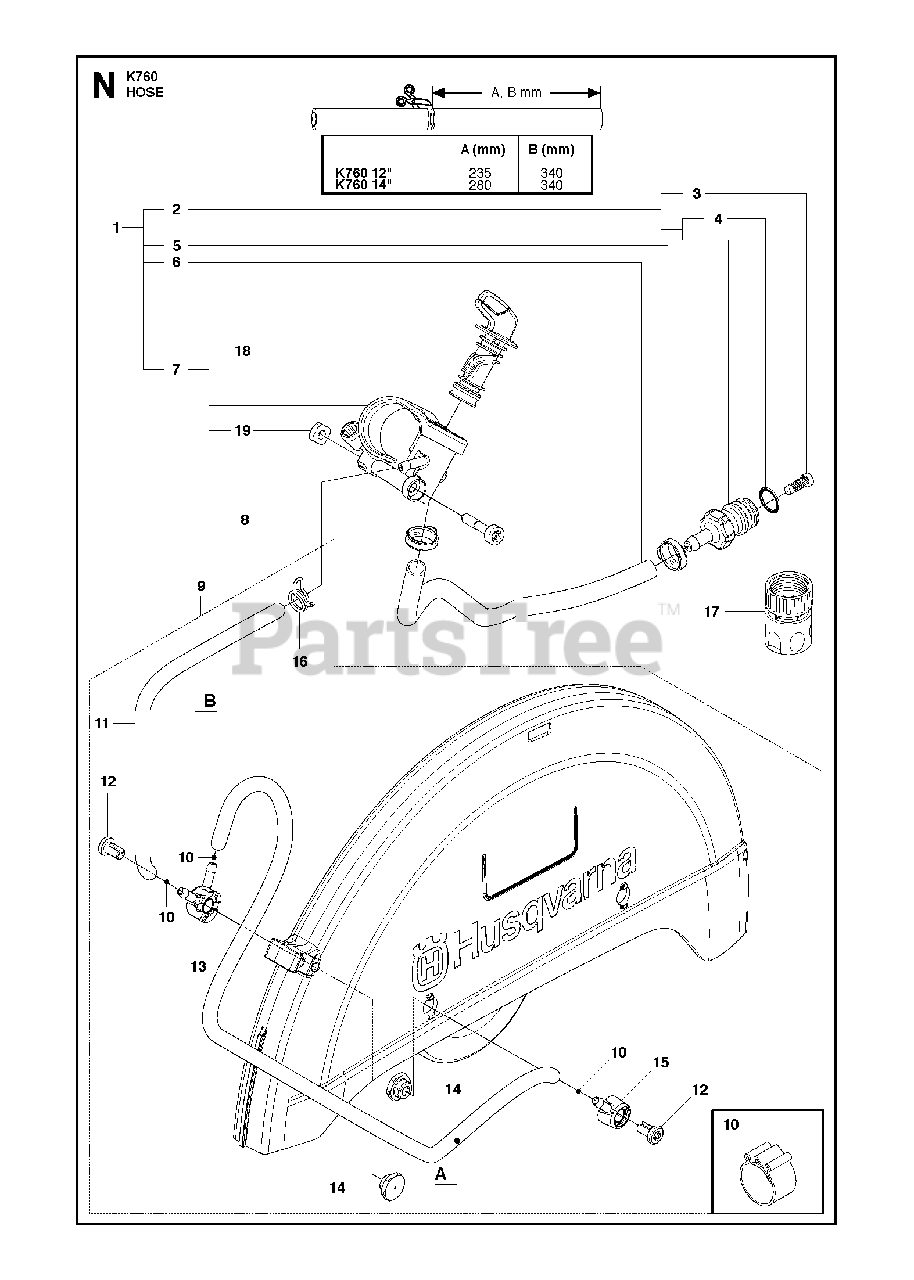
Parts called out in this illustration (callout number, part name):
1	HOSE KITIncl. 2, 5 - 7 & Hose Guard
2	NIPPLEIncl. 3, 4
7	VALVE ASSYIncl. 8, 18, 19
8	SCREW ITXSCM
9	HOSE KITIncl. 10 - 16
12	SCREW ITXSCM
17	COUPLERUSA, Canada
18	LEVER ASSYWith O-rings
